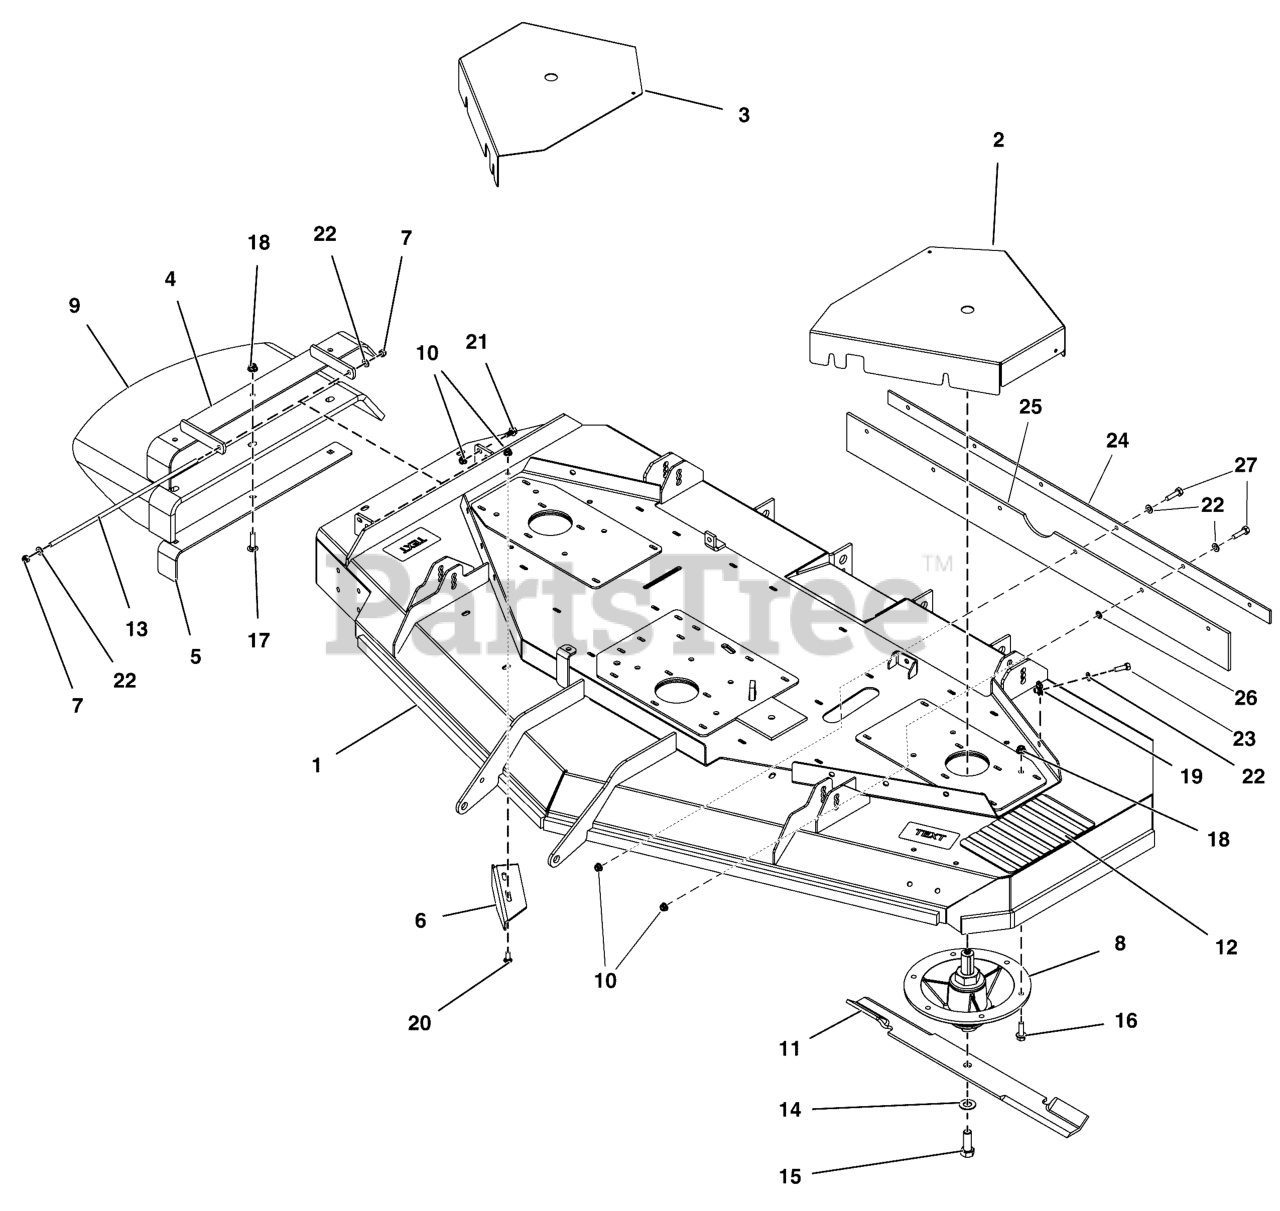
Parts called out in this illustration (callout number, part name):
1	DECK SHELL W/ DECALS, LMTD EDTN 72
2	GUARD, Belt
3	GUARD, Belt
4	FRAME, Chute
5	PLATE, Support
6	PLATE, DEFLECTOR, 72 - BLK
7	NUT, Hex Lock, Nylon, 5/16-24
8	SPINDLE ASSEMBLY
9	CHUTE, RUBBER DISCHARGE (5104442)
10	NUT, Flange Nylock, 5/16-18
11	BLADE, 25 X 25 X 2.50, HIGH LIFT (SET OF 3)
12	SAFETY WALK, 9.75 X 6.00
13	MOUNT, Chute
14	WASHER, Blade Bolt, 9/16"
15	BOLT, 5/8-11 X 1 3/4, GR 8
16	BOLT, Flange, 3/8-16 X 1 1/4
17	BOLT, Carriage, 3/8-16 X 1 1/2, GR5
18	NUT, Hex Flange, Nylock, 3/8-16
19	CLIP, BODY , 5/16-18 FOR 7 GA.
20	BOLT, 5/16-18 X 3/4, CARRIAGE, GD5, CZ
21	CAPSCREW, Hex Head, 5/16-18 x 3/4
22	WASHER, 5/16, Flat SAE, Zinc/Clear
23	CAPSCREW, Hex Head, 5/16-18 x 1
24	PLATE, Support
25	FLAP, STRIPER, 72 DECK
26	NUT, Push On, 5/16
27	BOLT, 5/16-18 x 1-1/4" TFL GD 5
